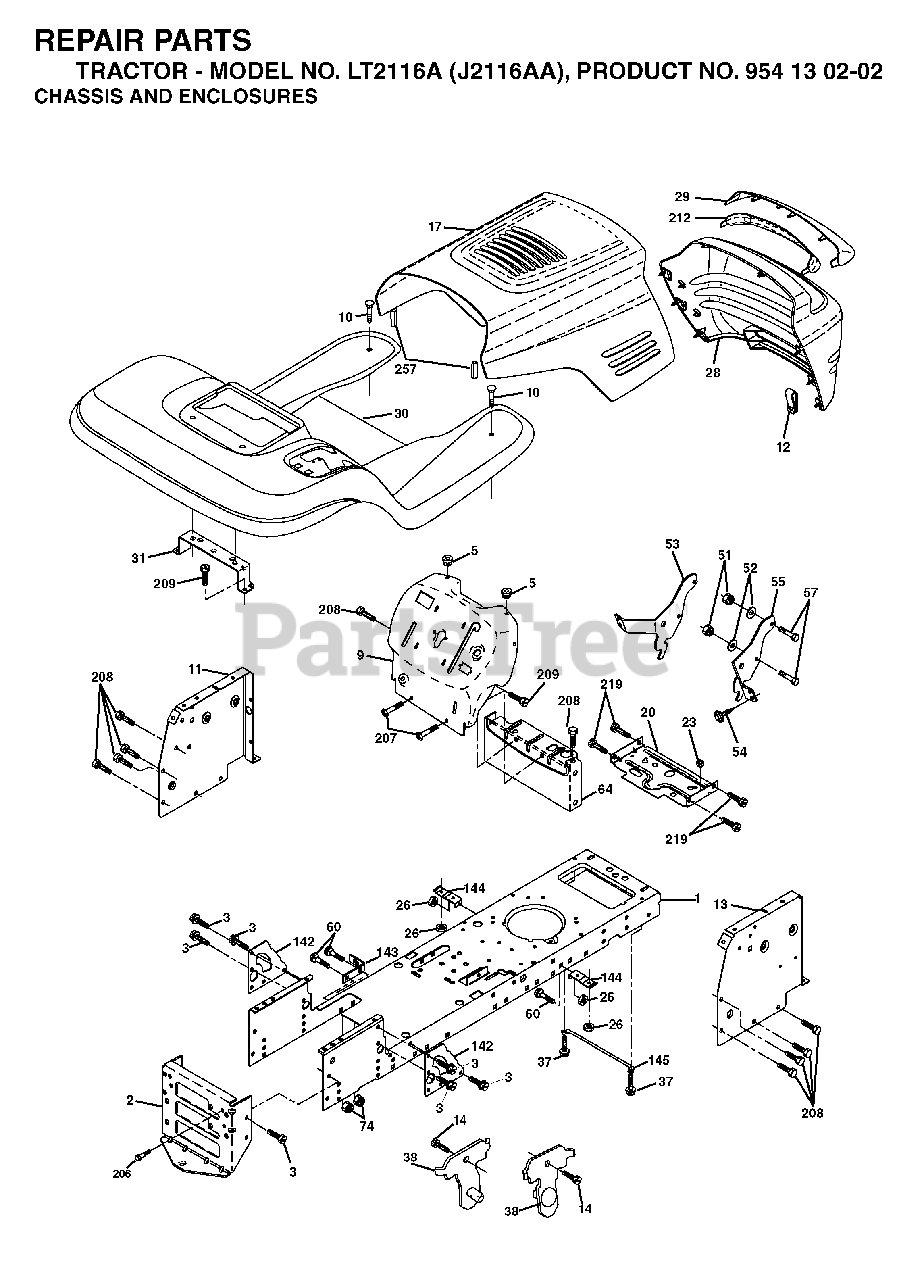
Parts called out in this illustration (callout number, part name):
1	CHASSIS STAMPING
2	DRAWBAR, 12GA
3	SCREW 3/8-16X3/4
5	BUMPER.RUBBER.HOOD
10	BOLT D
11	PANEL.DASH.LH.LTX
13	PANEL ASM, DASH RH
20	PLATE MTG.BATTERY/FUEL TANK
23	GROMMET T
26	NUT
38	BRACKET.ASM.PIVOT.MOWER.REAR
51	LOCKNUT
57	BOLT
64	DASH LOWER
74	LOCKNUT
142	PLATE REINFORCEMENT
143	BRACKET, SWAY BAR
144	BRKT, FOOT REST
145	ROD PIVOT CHASSIS/HOOD
206	SHOULDER BOLT 5/16-18TT
207	SCREW, 5/16-18 X 1/2
208	SCREW 3/8-16X1/2
209	SCREW, 3/8-16X3/4
219	SCREW
257	BUMPER.HOOD.LARGE.1.75"
